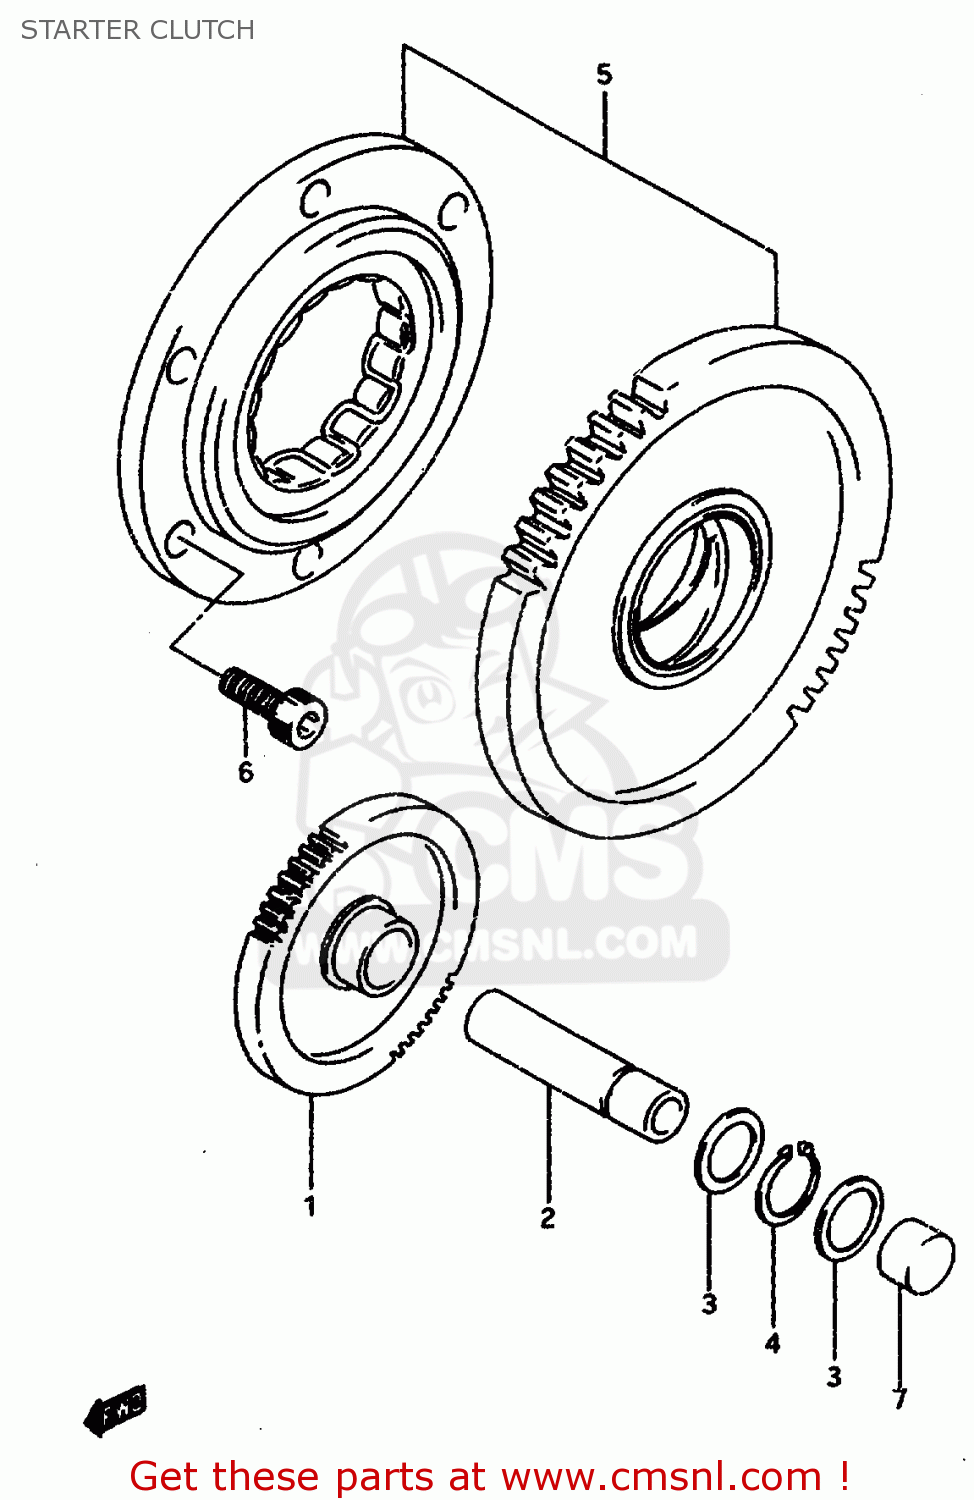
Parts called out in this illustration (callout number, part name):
1	GEAR,STARTER IDLE
2	SHAFT,STARTER IDLE GEAR
3	WASHER
4	CIRCLIP,12 MM
5	CLUTCH SET,STARTER
6	BOLT
7	PLUG
